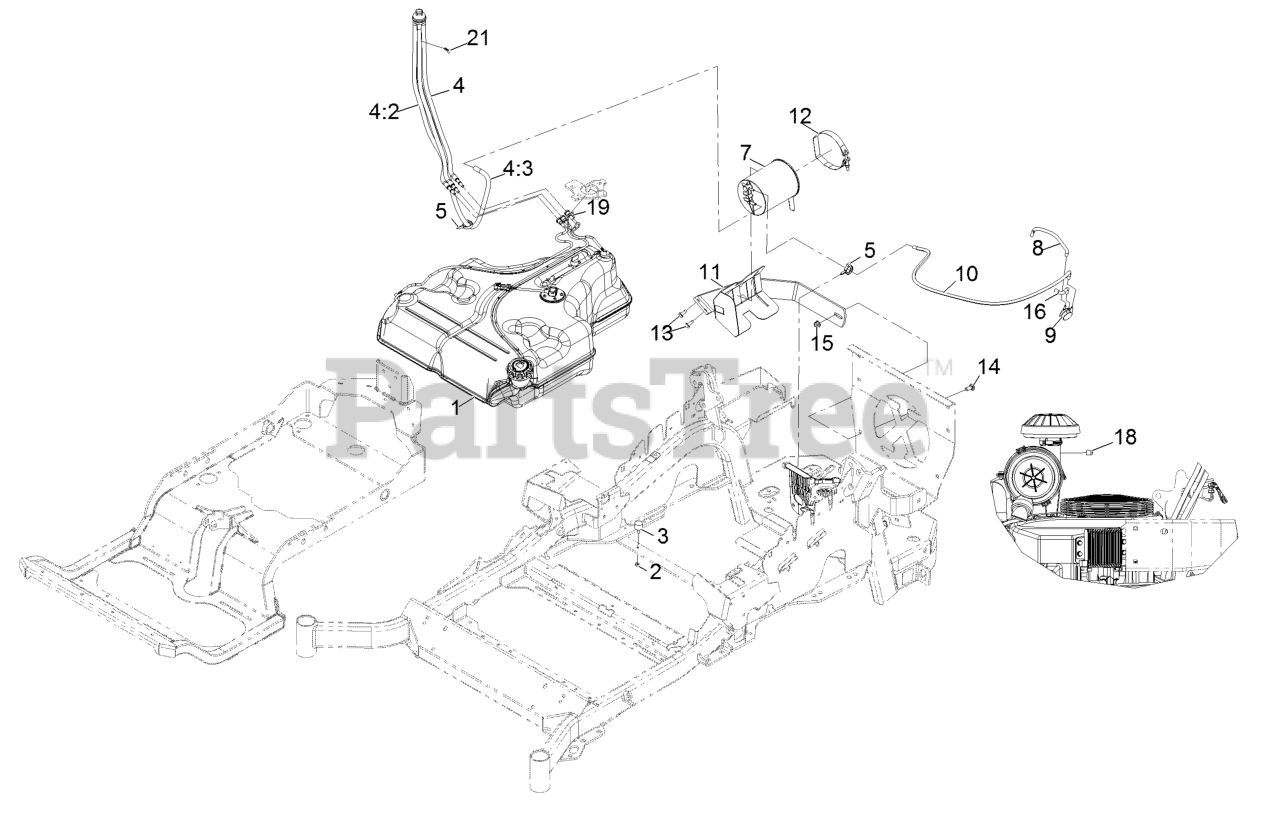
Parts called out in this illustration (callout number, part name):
1	Fuel Tank ASM
2	Nut-Jam 1/4-20
4	Fuel Manifold Vent ASM
4:2	Hose-Fuel Line 24"
4:3	Hose-Fuel
5	Clamp-Hose
7	Canister-Carbon, 1200Cc
8	Hose-Vent,Formed
9	Valve-Control, Vacuum
10	Hose,Vent,Formed
11	Mount-Canister
12	Clamp, T-Bolt
13	Screw-HWH 5/16-18 X 3/4 Tf
14	Bolt-Carriage 3/8-16 X 1
15	Nut-Nyloc 3/8-16 Flg
16	Hose-Vent, Formed
18	Plug-Port
19	Retainer-Line, Vapor
21	Plug-Plastic
